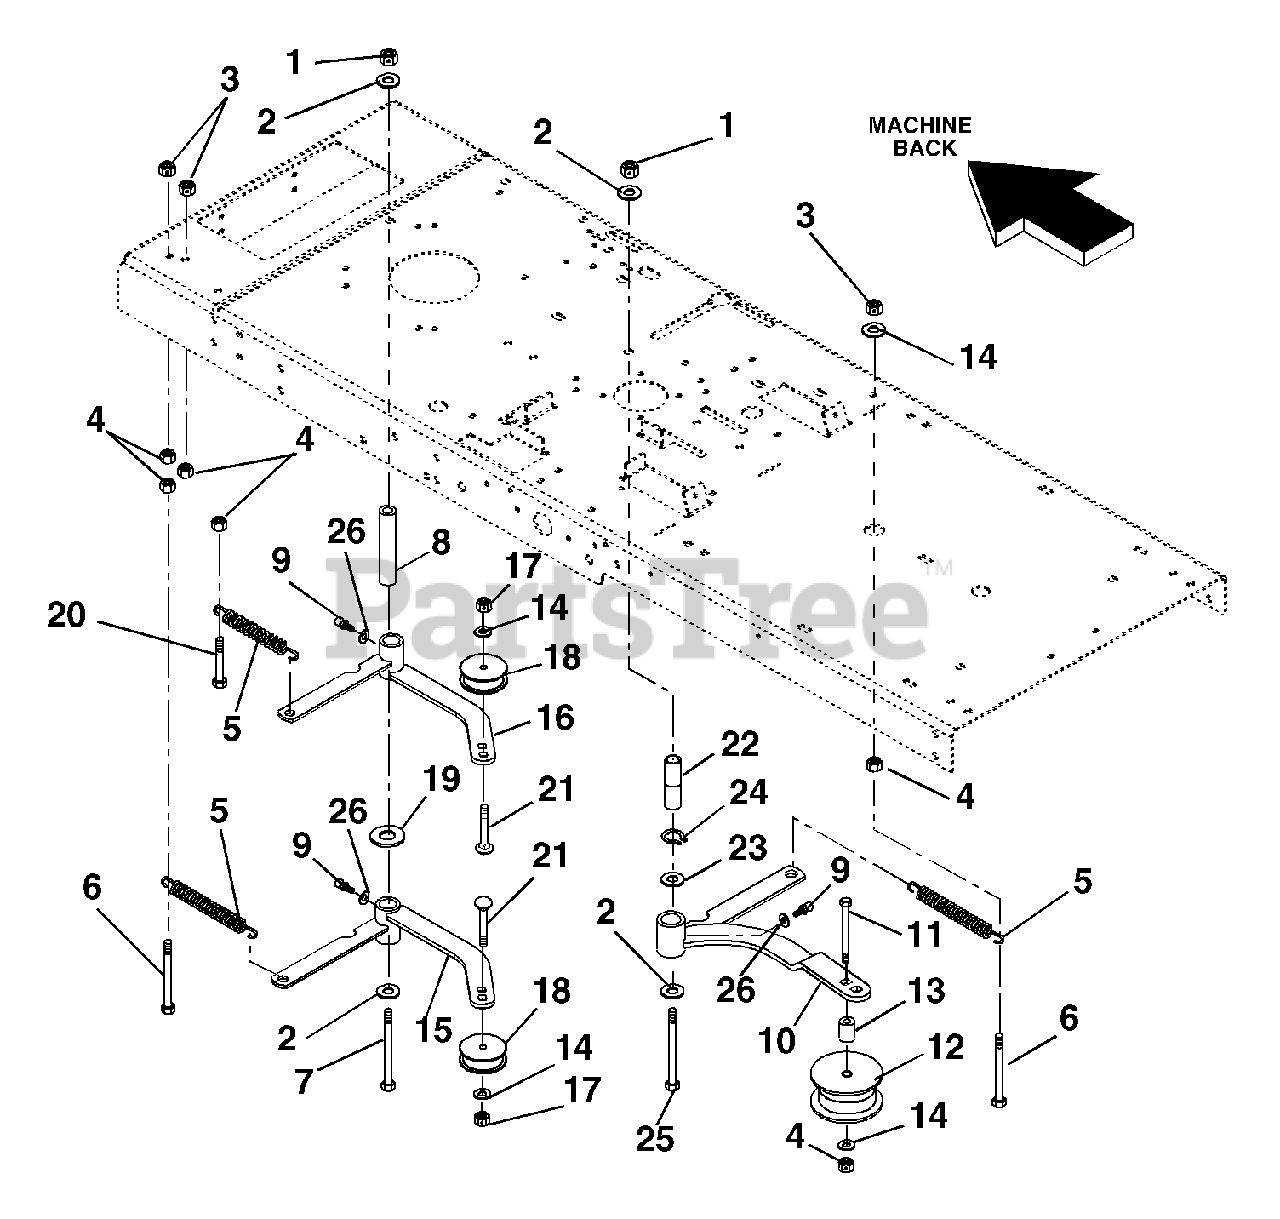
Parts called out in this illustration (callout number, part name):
1	Nut-Locking, Center .50-13
2	Washer-Flat, Steel .563 x 1.38 x .109
3	Nut-Locking, Center .38-16
4	Nut-Hex .38-16
5	Spring-Extension
6	Bolt-Hex .38-16 x 4.00 Grade 5
7	Bolt-Hex .50-13 x 5.50 Grade 5
8	Spacer-Idler Arm
9	Fitting-Lube .25-20 x .256
10	Weldment-Idler Arm
11	Bolt-Hex .38-16 x 4.50
11	Bolt-Hex .38-16 x 2.50
12	Idler-4.0 inch Diameter
13	Spacer-Idler 48 inch
14	Washer-Flat, Steel .406 x .812 x .065
15	Idler Arm Weldment Transaxle
16	Weldment-Jackshaft Idler Arm
17	Nut-Jam Lock .38-16
18	Idler-3.5 inch Diameter
19	Washer-Hardened
20	Bolt-Hex .38-16 x 1.75 Grade5
21	Bolt-Round Head Square Shank .38-16 x 1.50
22	Spacer-Idler
23	Washer-Flat-Steel .88 x 1.25 x .62
24	Ring-Retaining External .875 x .042
25	Bolt-Hex .50-13 x 4.50 Grade 5
26	Washer-Flat-Steel .250 x .562 x .049
